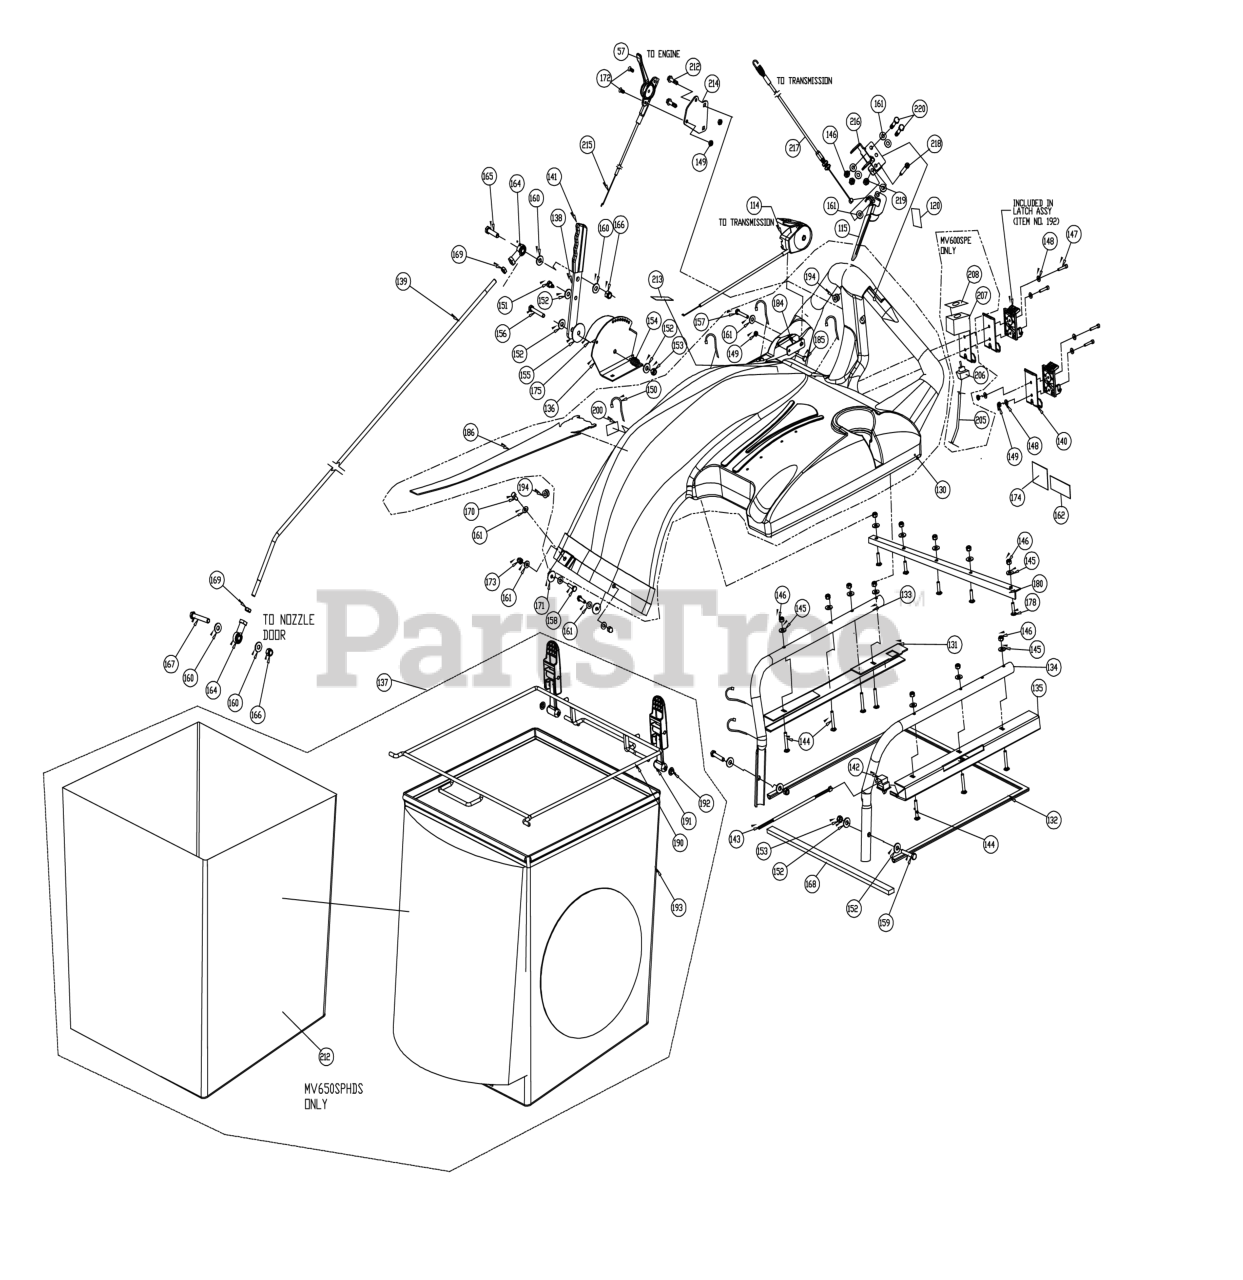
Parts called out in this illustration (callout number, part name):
57	CONTROL THROTTLE BLOWER
114	CABLE CONTROL SHIFT
115	HANDLE, MV CLUTCH CABLE
120	LABEL CLUTCH DRIVE
130	HOOD ASSY W/LABEL MV
131	BRACKET BAG CHANNEL RH W/SEAL MV VAC
132	SEAL 60" STRIP
133	HANDLE BRACE LID RH SP VAC
134	HANDLE BRACE LID LH SP VAC
135	BRACKET, BAG CHANNEL LH
136	BRACKET NOZZLE DOOR ADJ W.LABEL MV VAC
137	BAG W/ FRAME AND LATCHES (SEE ACCESSORY PRICELIST)
138	BAR LIFT NOZZLE DOOR W/GRIP MV VAC
139	ROD LIFT NOZZLE DOOR
140	PLATE BAG LATCH
141	GRIP LEVER 1" X 4.25"
142	SWITCH INTERLOCK
143	WIRE HARNESS, MV BAG SWITCH
144	BOLT CARRIAGE 1/4-20 X 1 3/4 Z/P
145	WASHER 1/4" FLAT Z/P
146	NUT LOCK 1/4"-20 HEX Z/P
147	SCREWCAP SOCKET HEAD #10-24 X 1"
148	WASHER #10SAE 7/32"X1/2"X1/16"
149	NUT LOCK LT #10-24 HEX
151	PIN-SCREW
152	WASHER 5/16" FLATWASHER Z/P
153	NUT LOCK 5/16"-18 HEX Z/P
154	SPRING LEVER GZ
155	WASHER FIBRE
156	SCREWCAP 5/16"-18X2" HCS ZP
157	SCREWCAP 1/4"-20X2 1/4" HCS ZP
158	SCREWCAP 1/4"-20 X 1" HCS ZP
159	SCREWCAP 5/16"-18X1 3/4" HCS ZP
160	WASHER 3/8"FC7/16"X1"X5/64"
161	WASHER 1/4"SAE9/32"X5/8"X1/16"
162	LABEL SAFETY PROTECT READ MANUAL
164	ROD END BALL JOINT 3/8" NF
165	SCREWCAP 3/8" - 16 X 1/2" HCS ZP
166	NUT LOCK 3/8"-16 HEX
167	SCREWCAP 3/8"-16X2 1/2" HCS ZP
168	SEAL 20.5" STRIP
169	NUT 3/8"-24 FIN HEX Z/P
170	SCREWCAP 1/4"-20X3/4" HCS ZP
171	WASHER FLAT FENDER 1/4"
172	SCREW MACHINE FLAT HD PHIL #10-24
173	NUT ACORN 1/4-20 HIGH CROWN
174	LABEL DANGER FLYING DEBRIS
175	LABEL NOZZLE DOOR MV VAC
178	BOLT CARRIAGE 1/4" X 3/4"
180	BRACKET HOOD FRONT STRAIGHTENER
184	PLATE SHIFT CONTROL ANTI ROTATE
185	SCREWCAP #10-24 X 1 1/4" HWF ZP
186	LABEL HOOD DECAL
190	ROD BAG WA
191	SEE: 840139
192	NUT PAL 5/16
193	BAG MESH MV W/VELCRO (SEE ACCESSORY PRICELIST)
194	GROMMET RUBBER 5/8" OD X 3/8" ID
212	DUST SOCK MV (SEE ACCESSORY PRICELIST)
213	LABEL THROTTLE BC
214	PLATE, MV THROTTLE CONTROL
215	CABLE, THROTTLE CONTROL 53.50" H
216	MV CABLE MOUNT WA
217	KIT, MV DRIVE CABLE W/GREASE
218	BOLT SHOULDER 1/4" X 1 3/4"
219	NUT #10-24 HEX NUT
220	SCREWCAP 1/4"-20X1 3/4" HCS ZP
221	SCREW PLASTITE 1/4-10 X 3/4 HWH ZP
